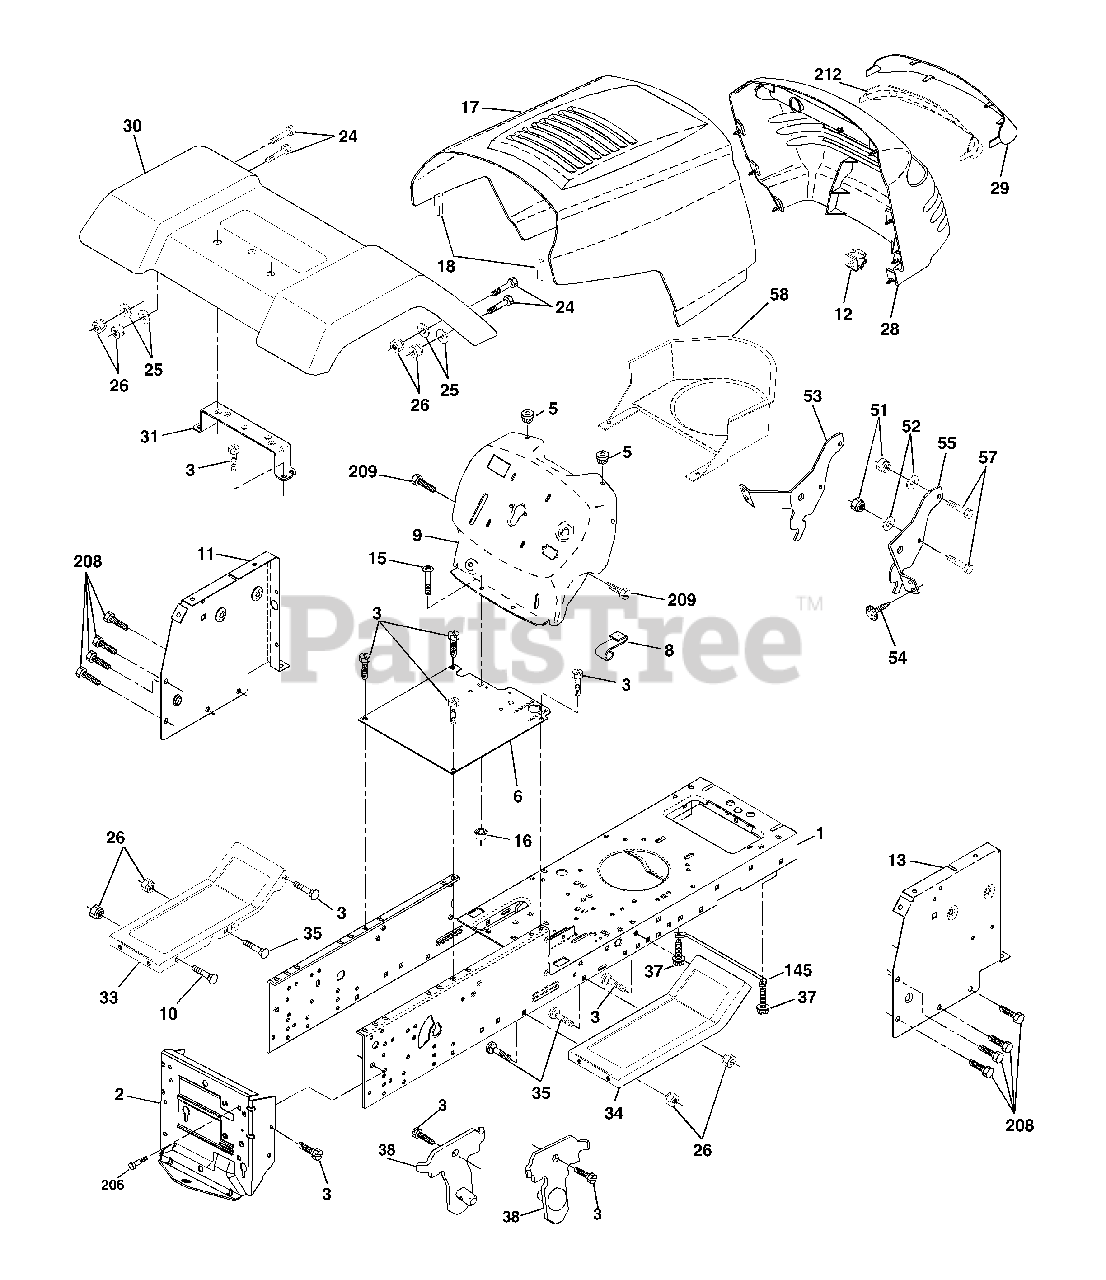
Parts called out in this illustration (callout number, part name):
2	Drawbar, Stretch
3	Screw 3/8-16 x 3/4
5	Bumper, Hood/Dash
6	Saddle Silkscreen Flt Sdl
8	Clip Retainer Slide-On
9	Dash
10	Bolt, Carriage 3/8-16 x 1
11	Panel Dash LH
12	Clip Tinnerman Grille P.L
13	Panel Slkscr Dash RH
15	Screw Mach TRHD 5/16-18uncx3/4
16	Nut Keps 5/16-18 Unc
18	Bumper Hood
24	Bolt Fin Hex 3/8-16unc X 1 Gr. 5
25	Washer 13/32 X 13/16 X 12 Ga
26	Nut Lock Hex w/Ins 3/8-16 Unc
28	Grille/Lens Asm.
29	Lens Grille Private Label
31	Bracket Fender Repl 109873x
33	Footrest Pnt LH Perf
34	Footrest Pnt RH Perf
35	Bolt Rdhd Sht Sqnk 3/8-16 X3/4
37	Screw Thdrol 5/16-18 x 1/2 TYT
38	Bracket Asm. Pivot Mower Rear
51	Nut Lock W/Insert 1/4-20unc
52	Washer 9/32 x 7/8x16 Ga.
53	Bracket Grille Lh
54	Screw Hex 8-18 x 7/8
55	Bracket Grille Rh
57	Bolt Fin Hex 1/4-20 unc x .75
58	Duct Air Engine PL/LT
145	Rod Pivot Chassis/Hood
206	Bolt Shoulder 5/16-18
208	Screw Thdrol 3/8-16 x 1/2
209	Screw Hex Wsh Thdrol 3/8-16
212	Insert Lens Reflect
